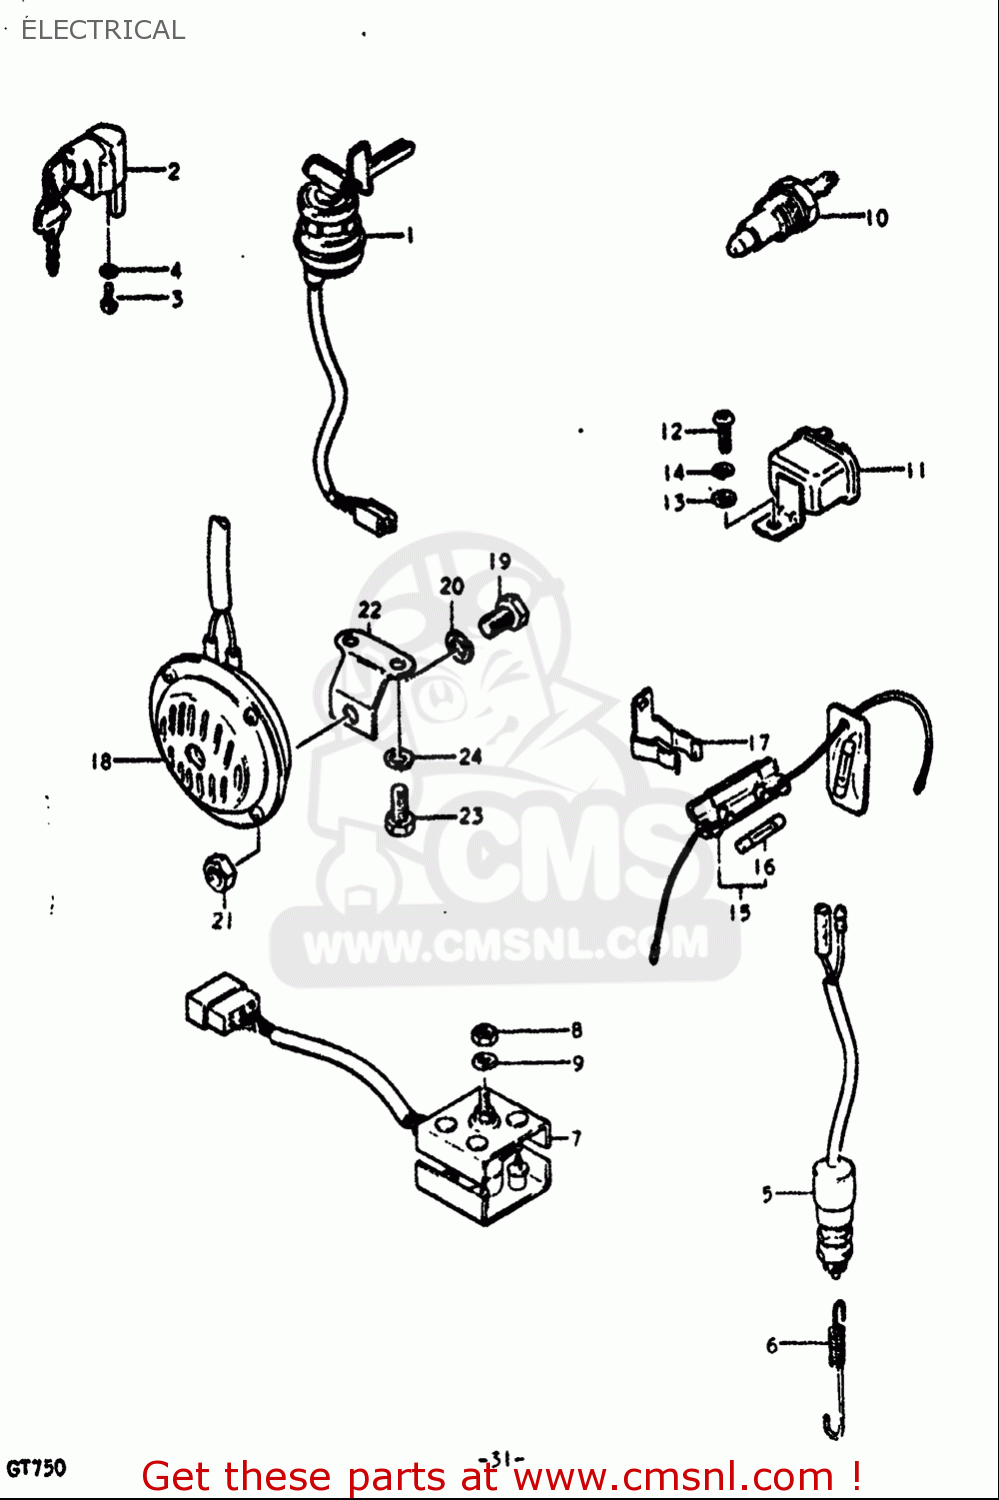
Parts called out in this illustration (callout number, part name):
1	SWITCH ASSY,IGNITION
2	LOCK ASSY,STEERING
3	SCREW
4	WASHER,LOCK
5	SWITCH ASSY,STOP LAMP
6	SPRING
7	RECTIFIER ASSY
8	NUT
9	WASHER,LOCK
12	SCREW
13	WASHER
14	WASHER,LOCK
15	CASE ASSY,FUSE
16	FUSE(20A)
19	BOLT
20	WASHER,LOCK
21	NUT
23	BOLT
24	WASHER,LOCK
